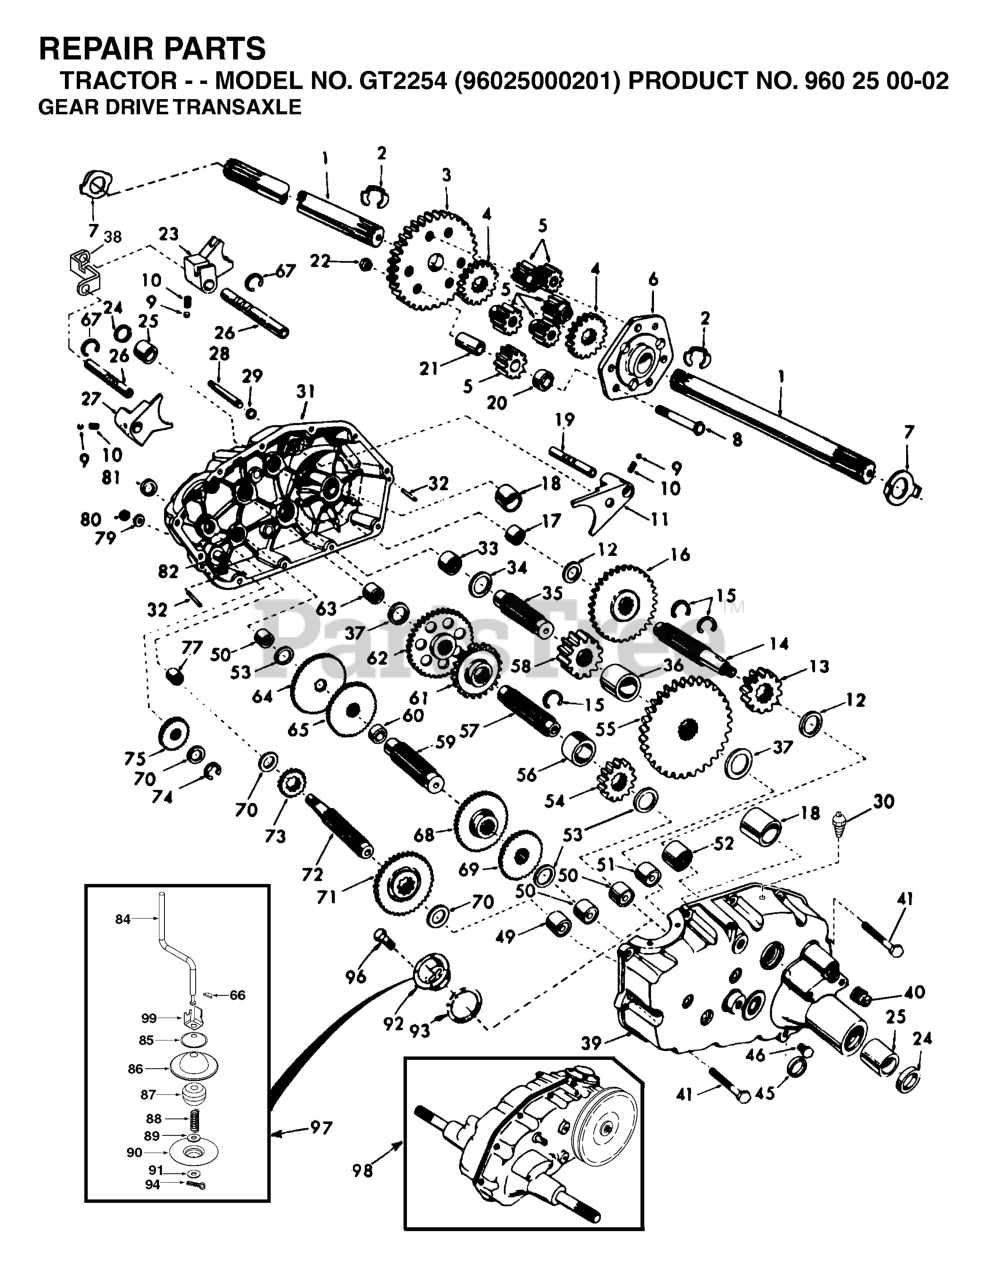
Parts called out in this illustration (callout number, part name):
1	AXLE SHAFT T
2	Ring, Klip Truarc #5304-75
3	FINAL GEAR T
4	DIFF GEAR T
5	DIFF PINION T
6	DIFF CARRIER T
7	WASHER.AXLE
8	Bolt, Hex Head 3/8-24 x 3-1/4 (1" Thread Length)
9	STEEL BALL KIT
10	SPRING
12	THRUST WASHER
13	RED PINION T
14	GEAR SHAFT
15	SNAP RING T
16	GEAR T
18	BEARING
21	PINION RS
22	GRIPCO NUT
24	OIL SEAL STD
25	BRNG. T
26	SHAFT SHIFT FORK
27	SHIFT FORK T
28	SHIFT SHAFT
29	SEAL.OIL.SHAFT.SHIFT.T
31	GEARCASE.RH.W/BEARING.GT
33	NEEDLE BRNG T
34	WASHER RACE BEARING THRUST
35	GEAR SHAFT T
36	GEAR SPACER T
39	GEARCASE.ASM.LH.W/BRG TRACTOR
40	Pipe Plug 1/2-14 N.P.T.
41	BOLT.5/16-18X1.25
49	BEARING TI
50	NEEDLE BRNG T
51	NEEDLE BRNG T
52	BEARING STD
53	BRNG RACE T
54	RED PINION T
55	RED GEAR T
56	PINION SPACER T
57	GEAR SHAFT T
58	FINAL PINION T
59	GEAR SHAFT T
61	RED PINION T
62	RED GEAR T
64	LOW SPEED GEAR T
65	GEAR.REVERSE.T
67	Snap Ring, Crescent Type
68	GEAR.SPEED.INTERMEDIATE.T/A
69	HIGH SPEED GEAR T
70	THRUST WASHER
71	CLUSTER GEAR T
72	SHAFT
73	LO SPEED PINION T
75	IDLER GEAR T
77	NEEDLE BEARING TI
80	NUT **
81	SEAL STD
82	SHAFT REVERSE IDL
84	GEAR SHIFT LVR T
86	COVER AND PIN T
87	GUIDE BALL T
90	SEAL.SHIFT
91	Washer 9/16 x 15/16 x 12 Gauge
92	GEAR SHIFT GATE T
94	COTTER PIN
97	LEVER.ASM.SHIFT
